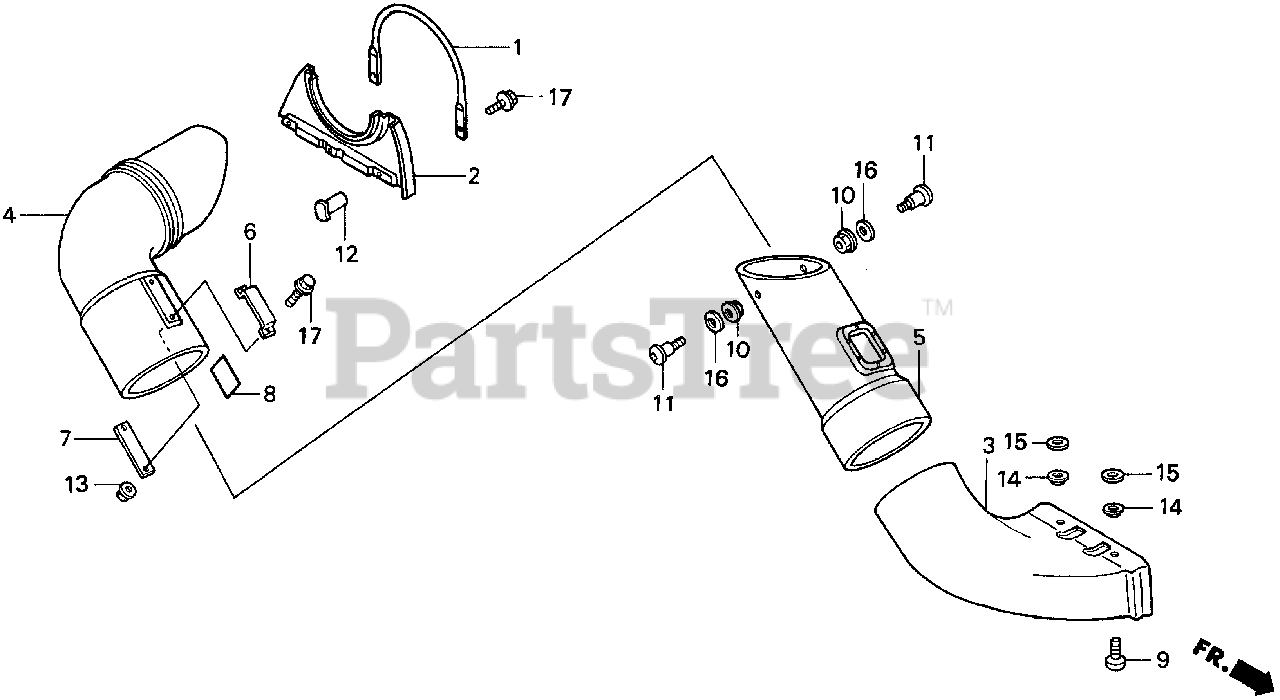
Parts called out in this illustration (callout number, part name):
1	SUPPORT, CHUTE
2	SEAL (NOT AVAILABLE)
3	CHUTE (LOWER)
4	CHUTE (UPPER)
5	CHUTE, MIDDLE
6	HANDLE, CHUTE (NOT AVAILABLE)
7	BASE, HANDLE
8	LABEL, CHUTE (ENGLISH)
10	NUT, NYLON INSERT LOCK (8MM) (NOT AVAILABLE)
11	BOLT, CHUTE
12	NUT, PIPE (6MM)
13	NUT, SELF-LOCK (6MM)
14	WASHER (8X24)
16	WASHER, PLAIN (8MM)
17	BOLT, FLANGE (6X16) Use from Engine SN 2056820.
